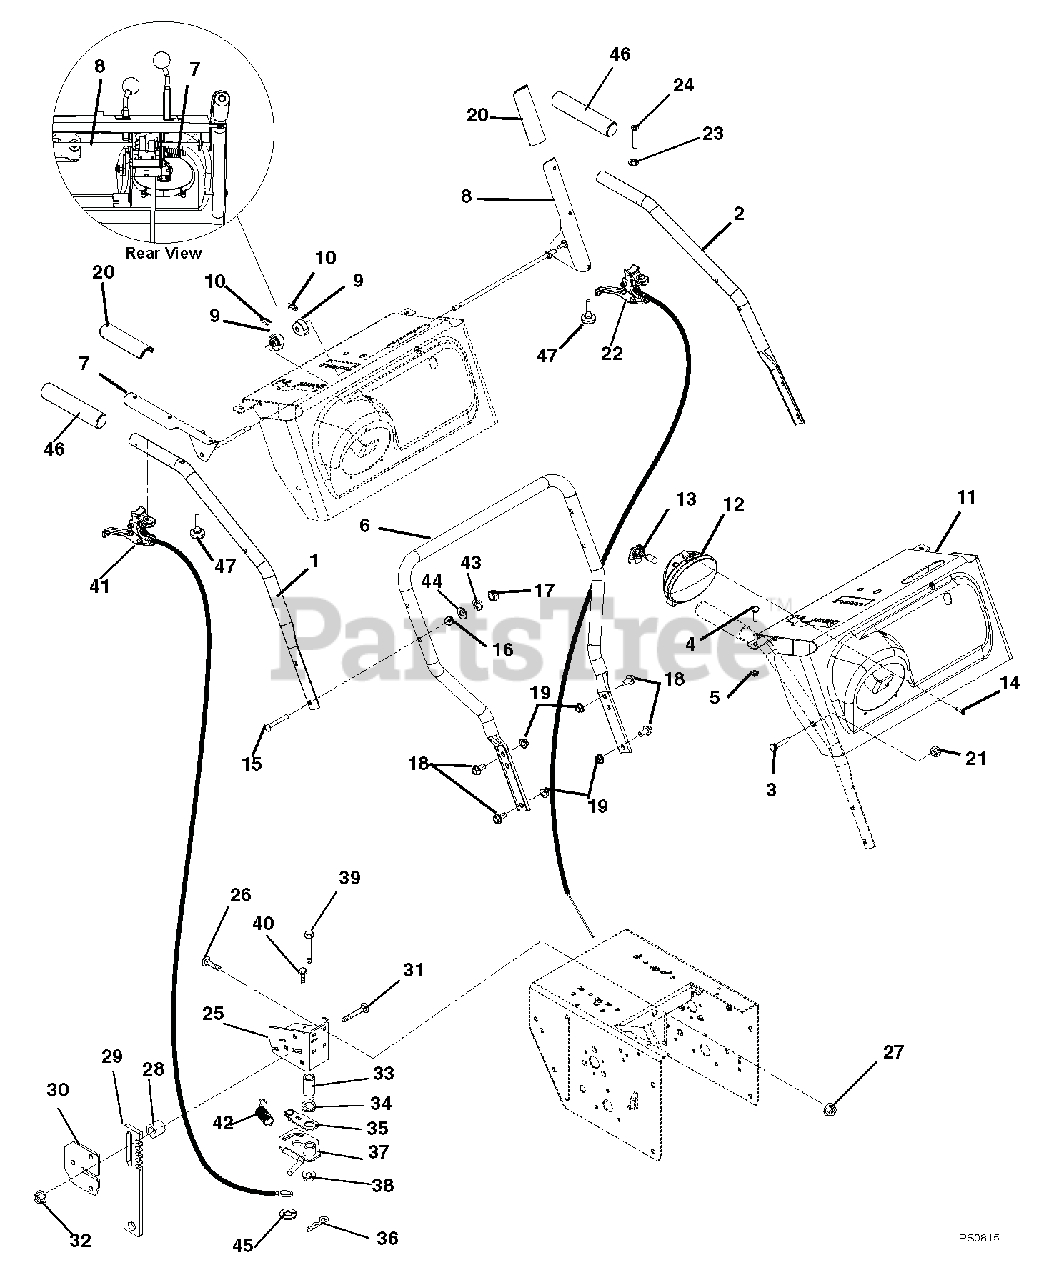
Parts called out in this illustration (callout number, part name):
1	HANDLEBAR, UPPER RH-W/HW
1	HANDLEBAR, UPPER-RH
2	HANDLEBAR, UPPER LH-W/HW
2	HANDLEBAR, UPPER-LH
3	@BLT-RDHDSQNK .31-18X1.75 G5YZ
4	BLT-RDHDXLSQNK.25-20X1.25 G5ZC
5	@NUT-LK-TOP-FLG .25-20 YWZC
6	HANDLEBAR, LOWER
7	LEVER, RH-ATTACHMENT
8	LEVER, LH-TRACTION
9	CAM, INTERLOCK
10	PIN, SPRING CLIP
11	PANEL-W/CONTROL HW DECAL
11	PANEL-W/CONTROL 12V DECAL
11	CONTROL PANEL W/DECAL - TRACK
11	PANEL-W/CONTROL 12VTRACK DECAL
11	PANEL-W/CONTROL DECAL
11	PANEL-W/CONTROL BRUSH DECAL
12	LIGHT, HALOGEN ASSY.
13	BULB, LIGHT-HALOGEN 20W
14	SCR-TAP 10-16X.75 HI-LO PPH
15	@BLT-RDHDSQNK .31-18X2.25 G5YZ
16	SPACER, HANDLEBAR
17	@NUT-LK-NYL .312-18 YWZC
18	BLT-SERHFWH .38-16X.75 YWZC
19	@NUT-LK-TOP-FLG .38-16 YWZC
20	GRIP, CLUTCH LEVER, LH AND RH
21	@NUT-LK-CTR .31-18 YWZC
22	CABLE, TRIGGER-REMOTE WHEEL
23	WSHR-LK-INT .250 TH TYA
24	SCR-MCH .25-20X1.50 OVAL HD
25	BRACKET, HEIGHT ADJUSTER-PRO
26	@BLT-RDHDSQNK .25-20X.75 G5YZ
27	@NUT-LK-TOP-FLG .25-20 YWZC
28	SPACER .50 X .32 X .42
29	STOP, HEIGHT ADJUSTER-PRO
30	PLATE, HEIGHT ADJUSTER
31	@BLT-RHDSHSQNK.31-18X1.25 G5YZ
32	@NUT-LK-TOP-FLG .31-18 YWZC
33	BSHG-SLV .385X.500X1.045
34	SG-TORS .067X.88
35	ARM, OVERTRAVEL
36	PIN-HAIR INT .06X.18X.77
37	LOCK, HEIGHT ADJUSTER
38	NUT-LK-CTR-FLG .38-16 YWZC
39	@BLT-HEX .38-16X1.75 GR5 YWZC
40	SCR-TAP .25-20X.50 HWH TR YWZ
41	CABLE, TRACK REMOTE
42	SPRING-EXT .047 X .438 X 1.85
43	@WSHR-LK .31X.078 REG YWZC
44	@WSHR-FL-STL.38X.875X.083 YWZC
45	@WSHR-FL-STL.281X.62X.065 YWZC
46	HANDLE GRIP
47	BUMPER, RUBBER - PULL MOUNT
